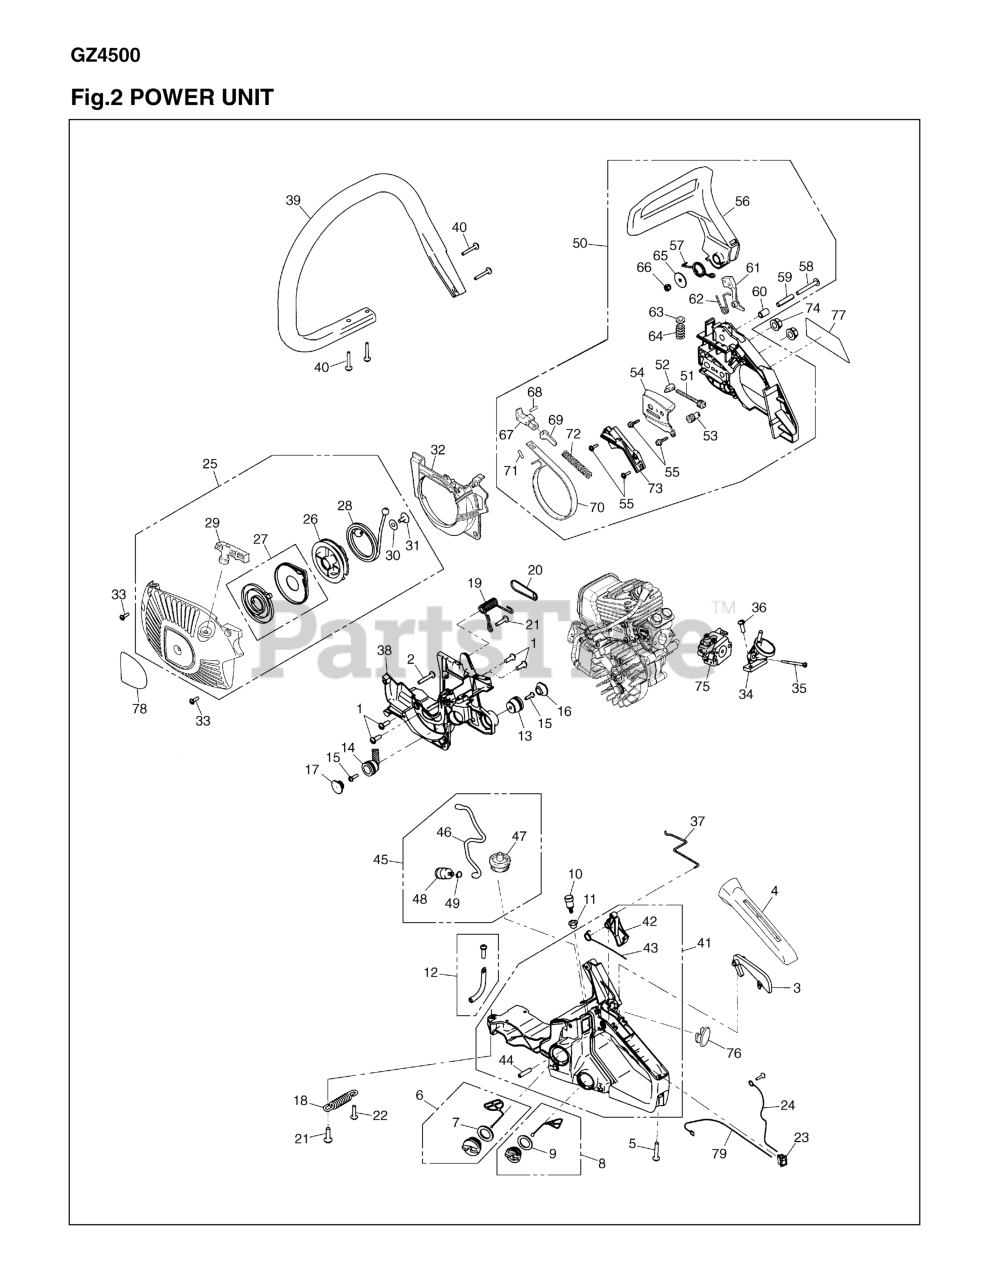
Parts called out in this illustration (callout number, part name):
1	SCREW (REPLACES 2616-24320)
2	SCREW
3	ARM (REPLACES 3356-33352)
4	COVER
5	SCREW
6	CAP ASSEMBLY
7	GASKET
8	CAP ASSY
9	GASKET
10	BREATHER ASSEMBLY
11	GROMMET
12	PIPE COMP
13	DAMPER (RPLS 2670-35110)
14	DAMPER COMPLETE
15	SCREW
16	CAP
17	CAP
18	SPRING, FRONT
19	SPRING, REAR
20	PLATE
21	SCREW (RPLS. 2671-32110)
22	SCREW (REPLACES 2616-24320)
23	SWITCH ASSEMBLY
24	CORD, SWITCH
25	STARTER ASSY
26	REEL
27	SPRING
29	KNOB (RPLS -75420)
30	WASHER (USE 181741)
31	SCREW (RPLS. 2671-32110)
32	COVER, FAN
33	SCREW
34	MANIFOLD
35	BOLT
36	SCREW
37	ROD
38	CASE, ENGINE
39	HANDLE, LEFT
40	SCREW
41	HANDLE, RIGHT ASSEMBLY
42	LEVER, THROTTLE
43	SPRING
45	PIPE ASSEMBLY
46	PIPE, FUEL
48	5500-85400 (RRLS. 1750-85300)
49	CLIP (REPLACES 2841-31280)
50	BRAKE ASSY
51	SCREW
52	NUT
53	GEAR
54	PLATE, GUIDE
55	SCREW
57	SPRING, RETURN
60	SPACER (RPLS -54210)
61	WEIGHT
63	PLATE, STOPPER
65	WASHER (RPLS -75410)
66	NUT (B)
67	LEVER, BRAKE COMPLETE
69	ARM, SLIDE(RPLS 2670-54410)
70	BAND, BRAKE
71	PIN
72	SPRING, BRAKE (RPLS. 50030121)
74	NUT
75	CARBURETOR ASSY
76	CAP
